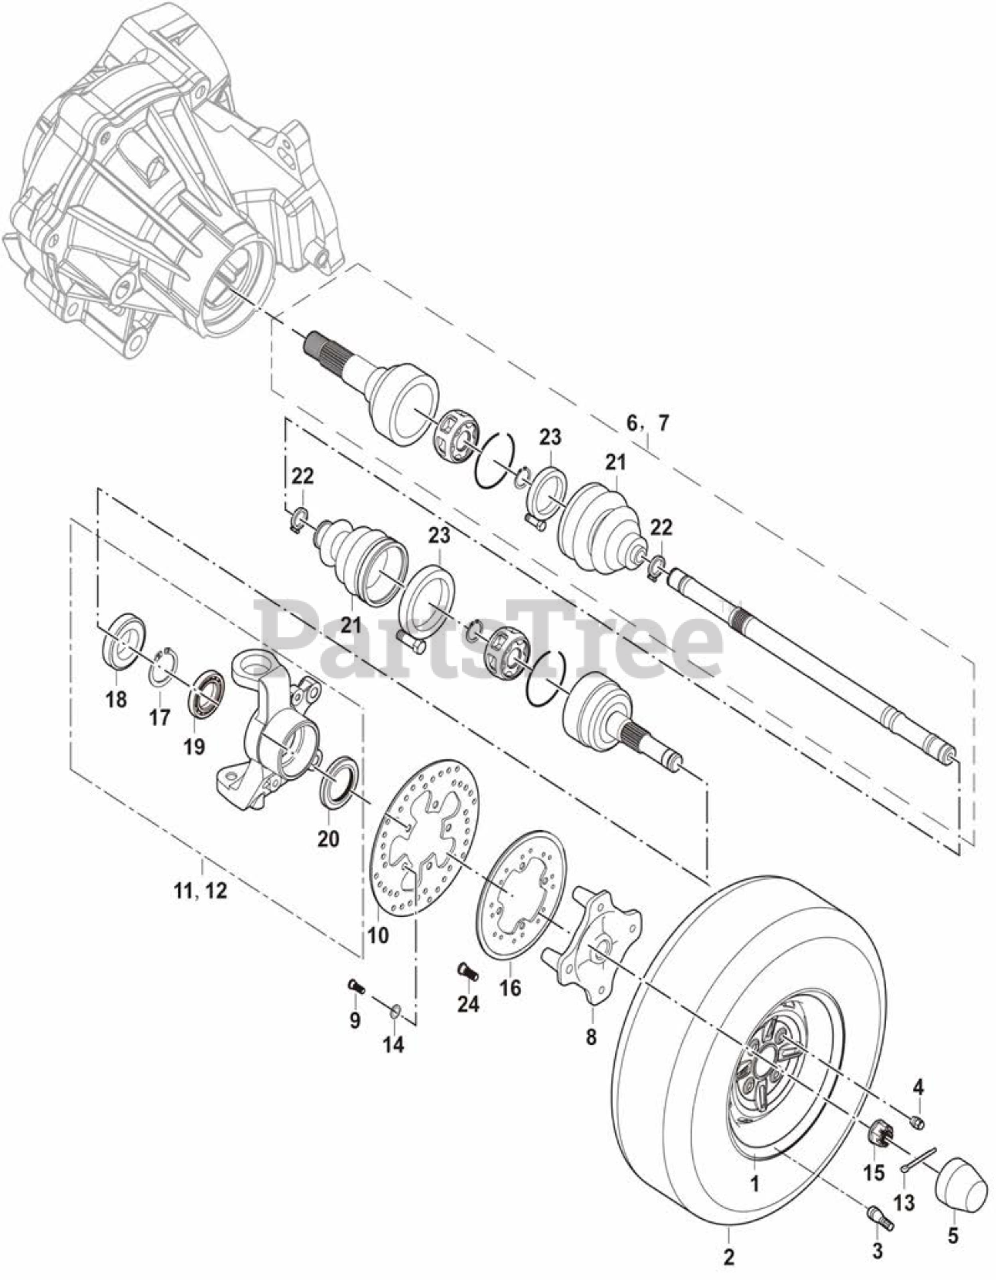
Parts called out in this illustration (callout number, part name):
2	Front Tire
3	valve core
4	Taper nut M10X1.25
5	trim cover F, wheel shaft
6	Front Left Semiaxle V
7	Front Right Semiaxle R
8	Connecting base assy,front hub
9	Cross Large Plate Head Screw M6X12
10	Brake Disc Protective Cover I
11	Front left steering knuckle arm
12	Front right steering knuckle arm
13	Cotter pin 3X40
14	Flat washer 6
15	Hexagon Thin Slotted Nut M24X1.5
16	Front Brake Pad
17	Clip d0=60
18	Front Knuckle oil seal inside 38X60X7
19	Front Knuckle bearing
20	Front Knuckle oil seal outward 38X55X7
21	Axle Rubber boot F
22	Axle Rubber boot clamp D
23	Axle Rubber boot clamp C
24	Inner hexagon cone bolt with pan M8
